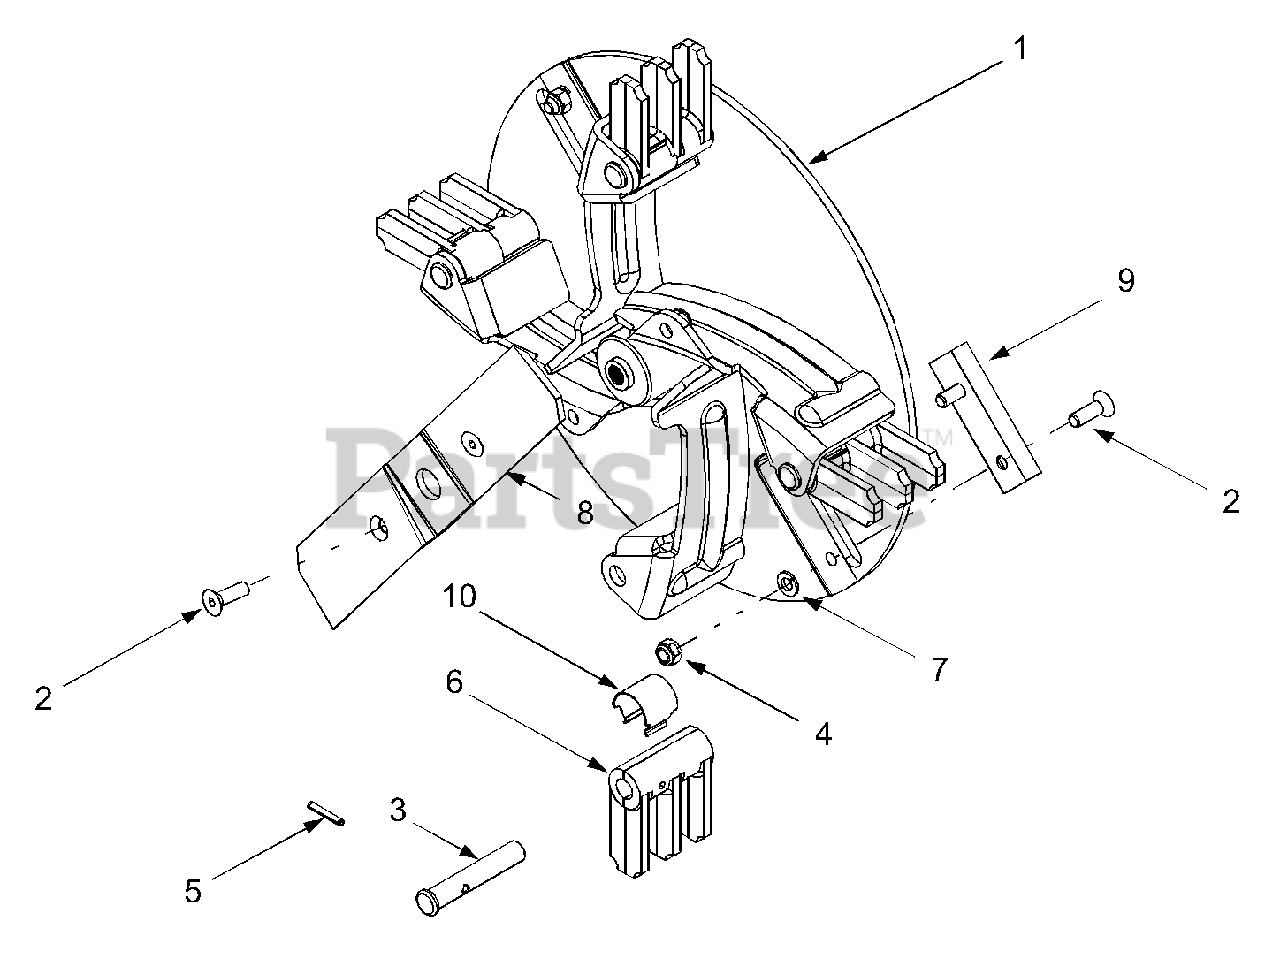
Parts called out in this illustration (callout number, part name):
1	Impeller Weldment
2	Machine Screw, 5/16-24 x 1.0
3	Clevis Pin, .496
4	Hex Lock Nut, 5/16-24
5	Spiral Pin, .156 x 1.0
7	Lock Washer, 5/16
8	Shredder Blade
9	Chipper Blade
10	Retainer Clip
